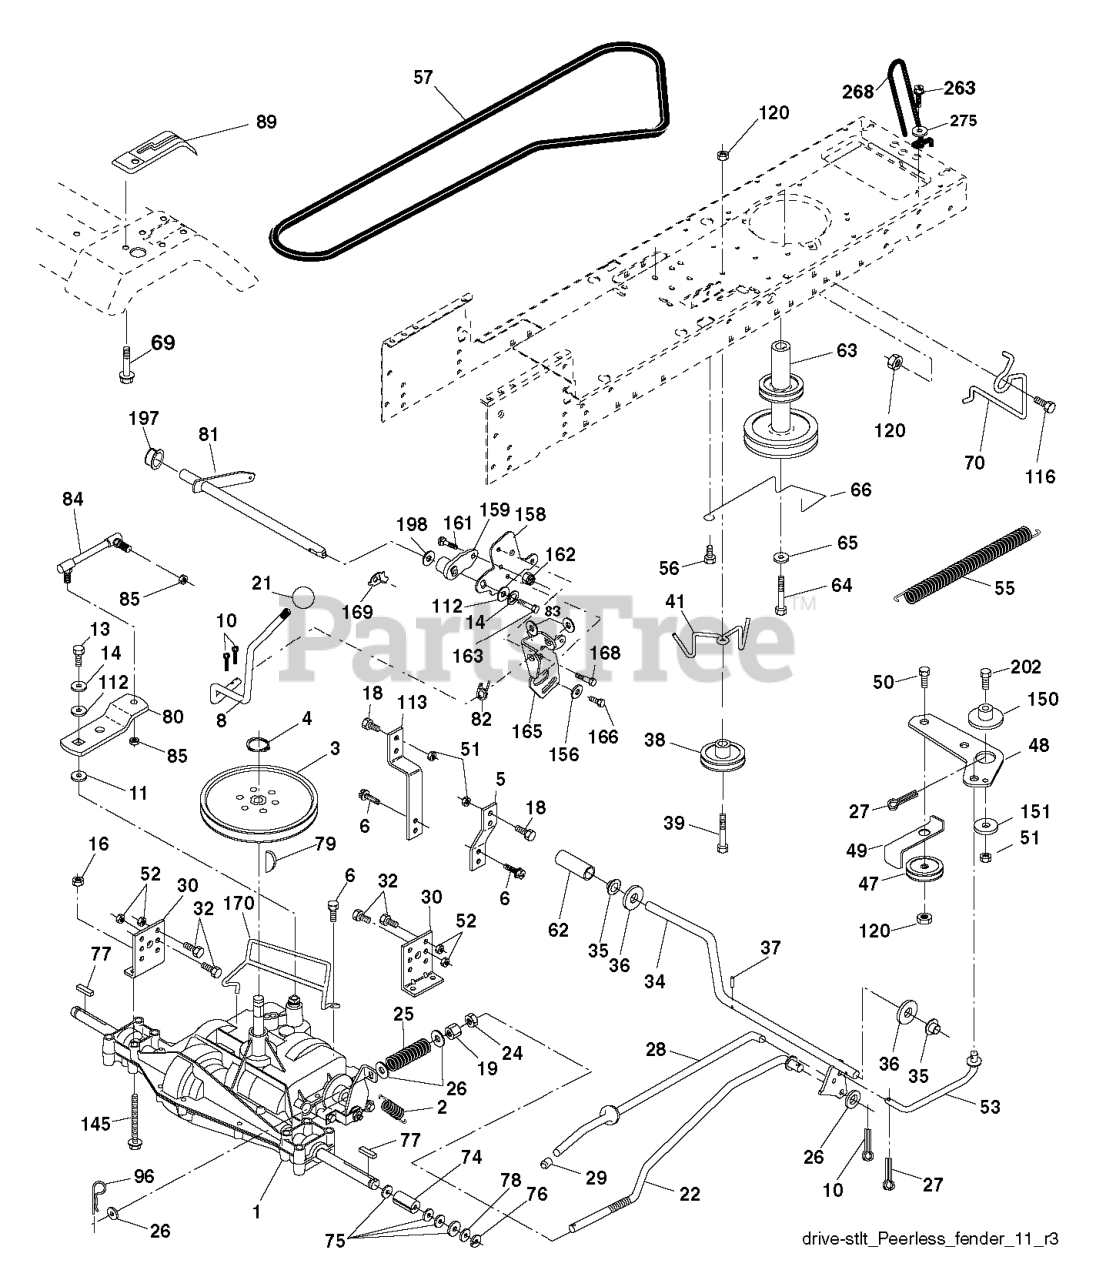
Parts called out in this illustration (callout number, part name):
1	CHASSIS STAMPING
2	DRAWBAR, 12GA
9	DASH
10	BOLT D
11	PANEL DASH LH
13	PANEL DASH RH
17	HOOD
20	PLATE BATTERY
26	NUT
28	GRILLE.STEALTH P/L.YTGT.GREY
29	LIGHTBOX.ASM.STV.DL.INC.HUSQ
30	FENDER STL W/CUPHOLDER
31	BRACKET.SUPPORT.FENDER
37	Screw 5/16-18 x 1/2 Hex, Self Tapping 5/16-18 x 1/2
38	BRACKET.ASM.PIVOT.MOWER.REAR
54	SCREW.HEX.WS.HD.8-18 X 7/8
59	BUSHING.1.375OD
60	Bolt - Rd. Hd. Sq. Neckiage 3/8 16 x 3/4
64	DASH LOWER
90	NUT.PUSH.3/16
142	PLATE REINFORCEMENT
143	BRACKET, SWAYBAR CHASSIS
144	BRKT, FOOT REST
145	ROD PIVOT CHASSIS/HOOD
154	BRACKET DASH STEALTH(R)
155	BRACKET DASH STEALTH LH
158	BRACKET PARKING BRAKE
159	GREY CUP HOLDER
161	EXTRUSION BUMPER (3 2) (2 2)
206	SHOULDER BOLT 5/16-18TT
209	SCREW, 3/8-16X3/4
213	SKIRT GRILLE LH
214	SKIRT GRILLE RH
217	CONSOLE FUEL WINDOW
278	SCREW
